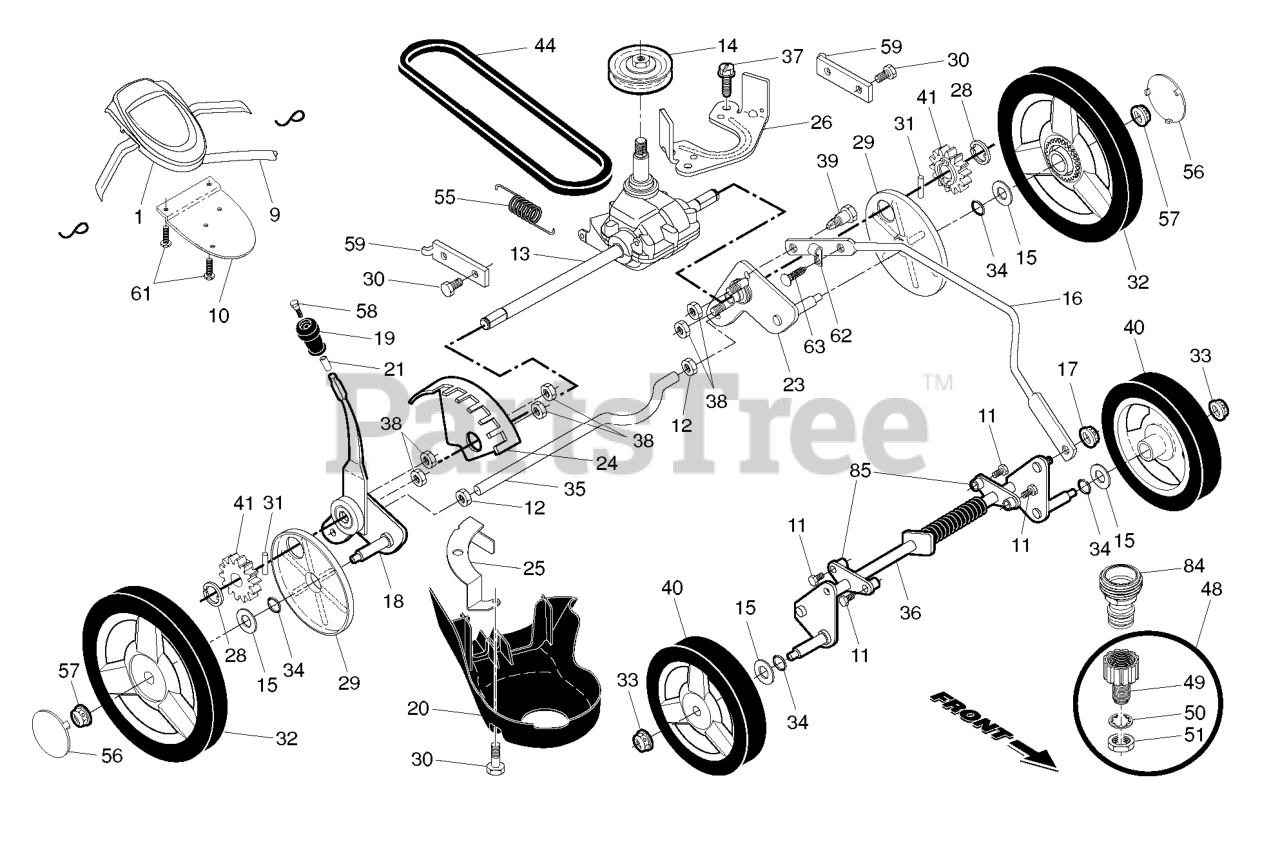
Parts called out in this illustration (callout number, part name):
1	RB CTRL.AW2.22+RGD.BS.GRY/BLK
9	CABLE.CONTROL.22RGD.GEN2
10	BRACKET.DRIVE.CONTR.GEN2.BLACK
11	SCREW.HX.13X.750
12	NUT.HEX.1/2-20
13	RP TRANSMISSION.22+.RGD.AW2/
15	WASHER.FLAT.1/2
16	ROD.CONNECTING.RGD.22+.HW.BLAC
17	NUT.LOCK.5/16-18
18	KIT.SEL.ASM.22+HI-WHEEL.ZINC
19	KNOB.SEL.SPRING.22+.SP.RIB.BLK
20	COVER.BELT.22.RGD
21	SCREW.PLASTIC.ANCHOR.5/16
23	ADJUSTER.ARM.ASM.AX.LT.SP.HW
24	BRACKET.WHL.ADJ.9.POS.W/PAD
25	BRACKET.DRIVE.COVER.RGD.BZP
26	BRACKET.TRANS.BELT.KEEPER.BZP
28	E-RING 7/16 RE
29	COVER.DUST.WHEEL.RGD.HW
30	BOLT.5/16HEX.WHS.HD
31	PAWL, DRIVE
32	WHEEL.11.ALPHA.GRY.EXT*
33	NUT.HEX.FLANGE.3/8-16.LO(3 2)
34	O-RING..070X.487.NEOPRENE
35	AXLE.REAR.RGD
36	AXLE.ASM.FRONT.RGD.CLEAR.ZINC
38	NUT.HEX.FLANGE.1/4
39	SHOULDER BOLT SEMI GIMLET PT.
40	WHEEL.8IN.H3SPK.ALPHA.
41	PINION.12.TEETH.RGD.22+HW
44	BELT.DRIVE.RGD.PLUS
48	KIT.WASH-OUT.PORT.ZINC.WALK
49	WASHOUT.PORT.ZINC.RGD.22+
50	WASHER.LOCK.INTERNAL.TOOTH
51	LOCKNUT.HEX.WITH.O-RING
56	HUBCAP.H.3SPK.GREY
57	NUT.HEX.FLANGE.3/8-16.LOCKNUT
58	SCREW.12-14X1.500
59	BRACKET.SUPPORT.22+RWGD.BZP
61	SCREW, PHILLIPS HEAD 10 X 5/8
62	CLIP.CABLE.BLK
63	FASTENER.PUSH.O.250X0.783
84	COUPLING.QUICK CONNECT
85	BRACKET.FRT.AXLE.SUPPORT
